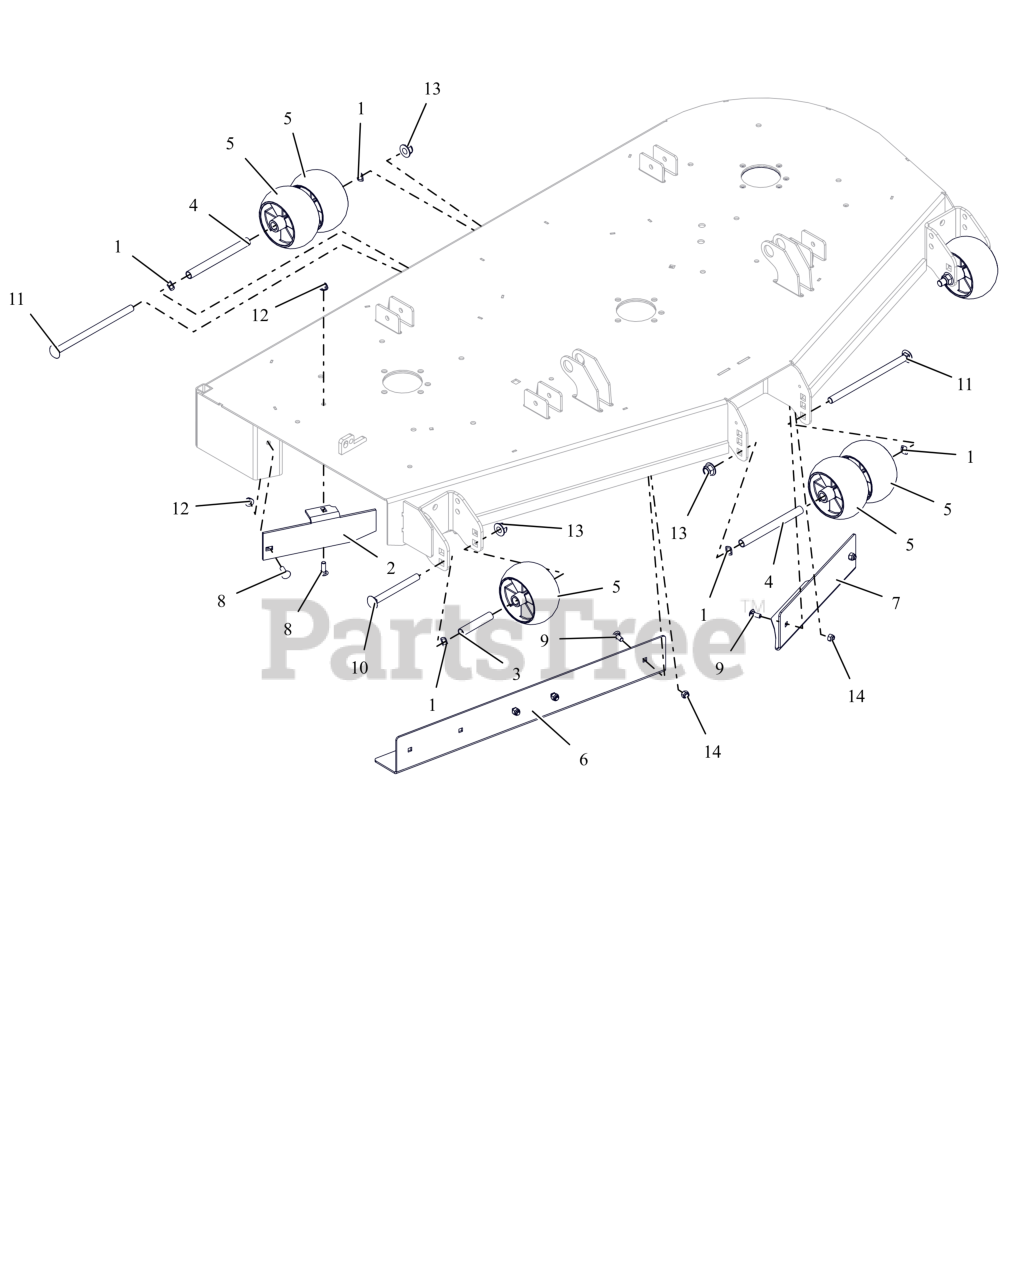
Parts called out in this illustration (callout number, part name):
1	WAVE WASHER .531X.781X.125FH
2	BAFFLE, 60" DISCHARGE
3	SPACER, .510X.625X3.35
4	SPACER, .510X.625X6.50
5	ANTI-SCALP WHEEL - 5X3 CTR
6	BAFFLE, 60" RH VACUUM (ORANGE)
7	BAFFLE, 60" LH VACUUM (ORANGE)
8	BLT,RHSN .31-18X1.00 G5 ZCC
9	BLT,RHSN .31-18X.75 G5 ZCC
10	BLT, RHSN .50-13X5.00 G5 ZCC
11	BLT, RHSN .50-13X8.50 G5 ZCC
12	NUT,LK-NYL-FLG .31-18 G5ZC120
13	NUT,NYL-FLG .50-13 GF ZCC
14	NUT,NYL .31-18 G5 ZCC
